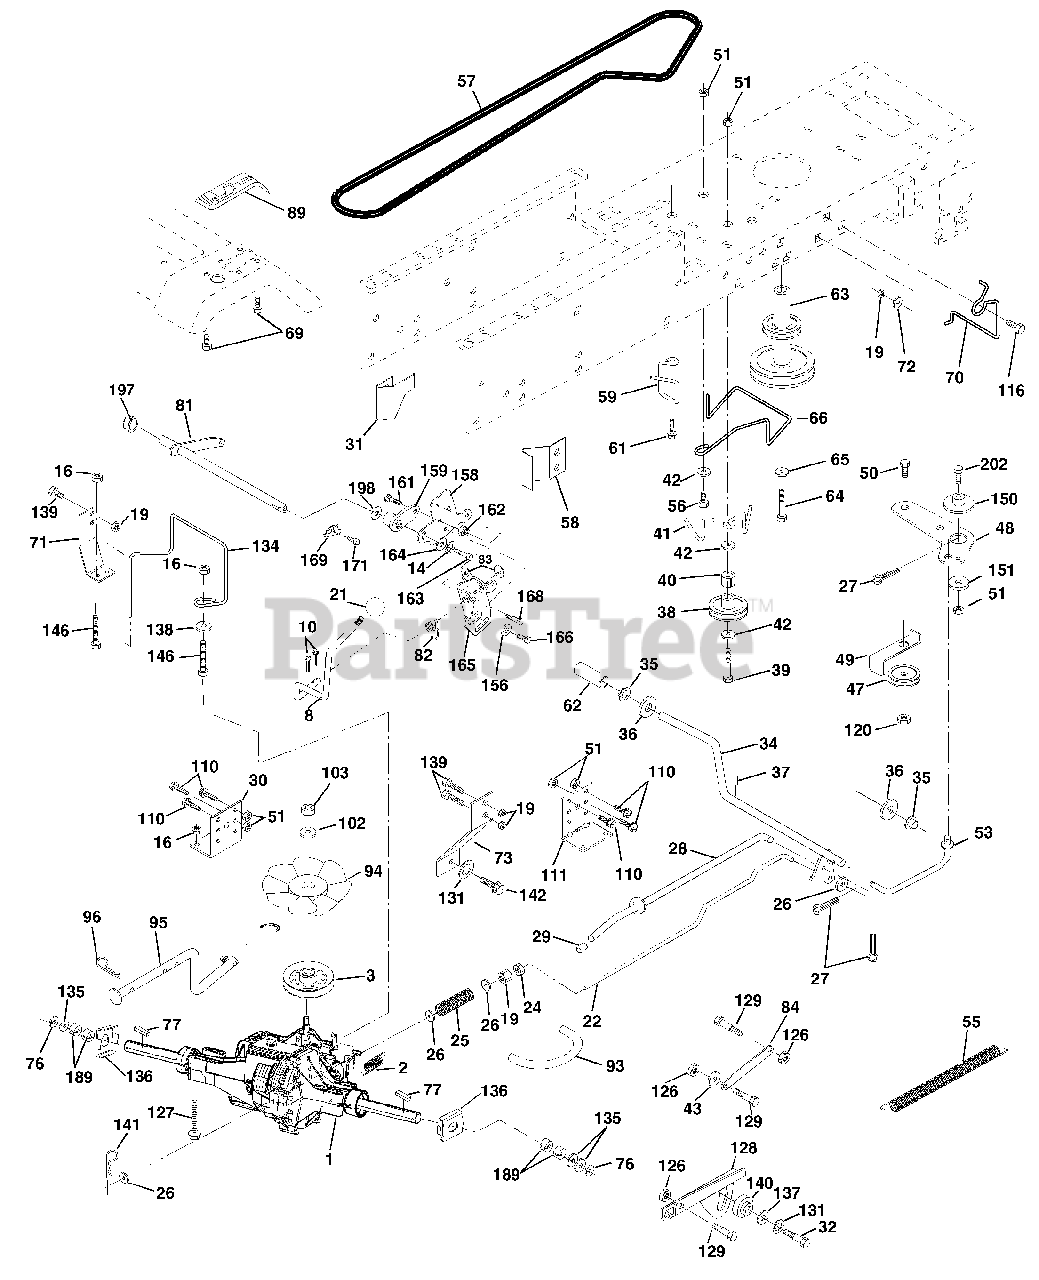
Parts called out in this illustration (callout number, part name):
2	Spring, Brake Return
3	Pulley, Hydro
8	Rod Shift Fender Adjust Yt
10	Pin, Cotter 1/8 x 1
14	Washer Lock Hvy Helical
16	Nut Lock Hx w/Ins. 5/16-18 Unc
19	Nut, Lock Hex w/Ins. 3/8-16 UNC
21	Knob
22	Rod, Brake
24	Nut, Hex Jam 3/8-16
25	Spring, Rod, Brake
26	Washer 13/32 x 13/16 x 16 Ga.
27	Pin, Cotter 1/8 x 3/4
28	Rod, Brake, Park
29	Cap, Brake Parking Black
30	Bracket, Transaxle, L.H.
31	Keeper, Belt, Transaxle, L.H.
32	Bolt Hex Hd. 5/16-18 Unc x 3/4
34	Shaft, Foot Pedal
35	Bearing Nylon
36	Washer 21/32 x 1 x 16 Gauge
37	Pin, Roll 3/16 x 1
38	Idler, Flat
39	Bolt Rdhd 3/8-16 Unc x 3
40	Spacer
41	Keeper, Idler
42	Washer 13/32 x 13/16 x 12 Gauge
43	Bolt Shoulder 5/16-18 Unc
47	Pulley, Idler
48	Bellcrank Clutch Grnd Drv Stl
49	Retainer, Belt
50	Bolt, Hex 3/8-16 x 1-1/2
51	Nut, Crownlock 3/8-16
53	Link, Clutch
55	Spring, Return, Clutch
56	Bolt, Hex 3/8-16 x 1-1/4
57	V-Belt, Drive
58	Keeper, Belt, Transaxle, R.H.
59	Keeper Belt Centerspan
61	Screw 3/8-16 x 3/4
62	Cover, Foot Pedal
63	Pulley, Engine
64	Bolt, Hex 7/16-20 x 4-1/4
65	Washer, Lock Hvy Hlcl Spr 7/16
66	Keeper Belt Engine F-proof
69	Screw Hex Wsh Hi-Lo 1/4-1/2 Unc
70	Keeper Belt Engine
71	Strap Torque Lh Hydro-3000
72	Washer 13/32 x 1-1/4 x 12 Ga.
73	Strap Torque Rh Hydro-3000
76	E-Ring
77	Key Square 1/4 x 2
81	Shaft Asm Cross Tapered
82	Spring, Torsion
83	Washer 17/32 x 3/4 x 16 Gauge
84	Link Transaxle
93	Line Fuel Hydro
94	Fan Hydro
95	Control Asm Bypass Hydro-3000
96	Retainer Spring 1" Zinc/cad.
102	Washer Belliville 1/2 x 1-1/2
103	Nut Hex Jam Toplock 1/2-20 Unf
110	Bolt Hex 3/8-16 x 3/4
111	Bracket, Transaxle, R.H.
116	Bolt Rdhd Sq Neck 3/8-16 x 1/25
120	Nut Lock Flg. 3/8-16 Unc
126	Nut Lock 5/16-18 Nc Thd
127	Bolt Hex Flghd 5/16-18 x 3.0 Gr. 5
128	Bracket Neutral Adjust HG-3000
129	Bolt Shoulder 5/16-18 Unc
131	Washer Lock 5/16
134	Rod Actuator Bypass Hydro-3000
135	Washer 1-1/32 x 1-5/8 x 16 Gauge
136	Washer Axle Flange
137	Washer 11/32 x 3/4 x 12 Ga.
138	Washer 11/32 x 1.25 x 16 Ga.
139	Bolt Fin Hex 3/8-16 x 3/4
140	Bushing Pinion Sector
142	Bolt 5/16 x 24 x 1
146	Bolt Hex Flghd 5/16-18 x 2-1/4
150	Spacer
151	Washer 13/32 x 2 x 10 Ga.
156	Washer Srrted 5/16ID x 1.125
158	Bracket Shift Mount
159	Hub Tapered Flange Shift Lt
161	Bolt Rdhd Sqnk 1/4-20 x 3/4 Gr 5
162	Nut Crownlock 1/4-20 Unc
163	Bolt Hex Fin 1/4-20 Unc x 1 Gr 5
164	Washer 5/8 x .281 x 10 Ga
165	Bracket Pivot Lever
166	Screw 5/16-18 x 5/8
168	Bolt Shoulder 5/16-18 x .561
169	Plate Fastening Lt
171	Screw Thdrol 3/8-16 x 1/2 Ty-Tt
189	Washer Spacer Axle
197	Nyliner Snap-In 5/8" Id
198	Washer Nyl 7/8 Id x .105
202	Bolt Carr Sh 3/8-16 x 1-1/2 Gr.5
